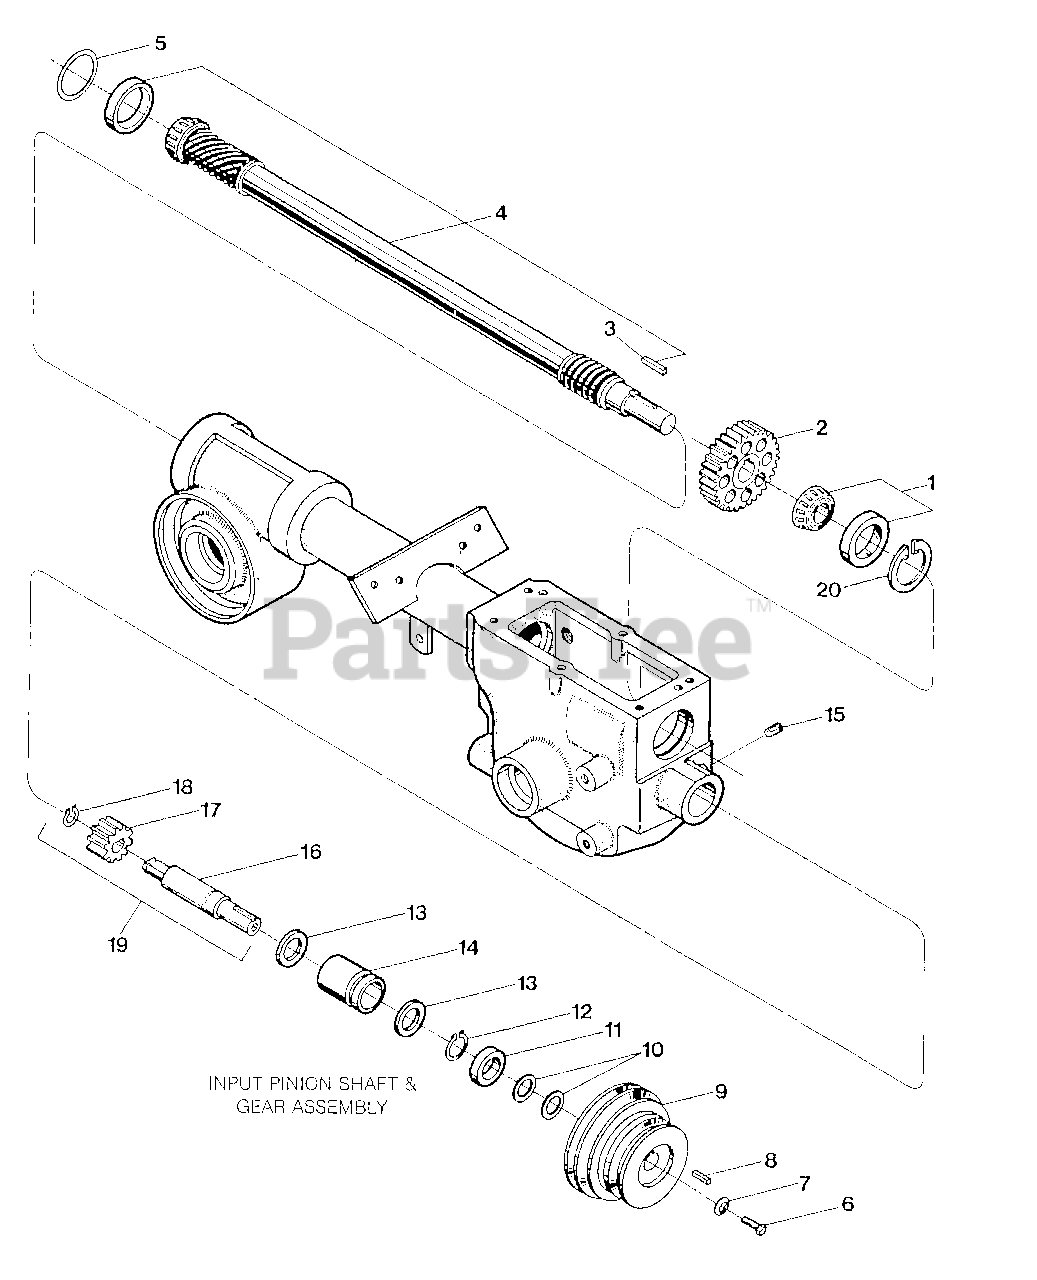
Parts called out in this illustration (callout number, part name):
1	KIT-BRG CONE&RACE-DRIVESHAFT (FRONT OF DRIVE SHAFT)
2	GEAR-SPUR 30 TEETH
3	KEY-.188 SQX1.0
4	KIT-DRIVESHAFT SMFR
4	KIT-DRIVESHAFT
5	SHIM-1.75X1.5X.01
5	SHIM-1.75X1.5X.03
5	SHIM-1.75X1.5X.005
6	SCR-HH 5/16-24X.75 G5 ZP
7	WASHER-.827X.331X.098
8	KEY-.188 SQX1.0
9	PULLEY-TRANS MACH, 3 GROOVES (TWO FOR FORWARD SPEEDS; ONE FOR REVERSE SPEEDS)
10	WASHER # .875 X .65 X .06
11	SEAL-PINION SHAFT PT/85030/00
12	RING-RETAIN EXT .707 ID (SNAP-IN)
13	WASHER-1.022X.752X .059
14	BUSHING-1.24X.75X1.8 GRVD
15	SCR-SS 5/16-18X.375
16	SHAFT-PINION(P-V)
17	GEAR-PINION P/M
18	RING-BOWED EXT .461 ID
19	PINION W/GEAR&SNAP RING (INCL. ONE EACH OF 16-18)
20	RING-RETAINING 5000-181
